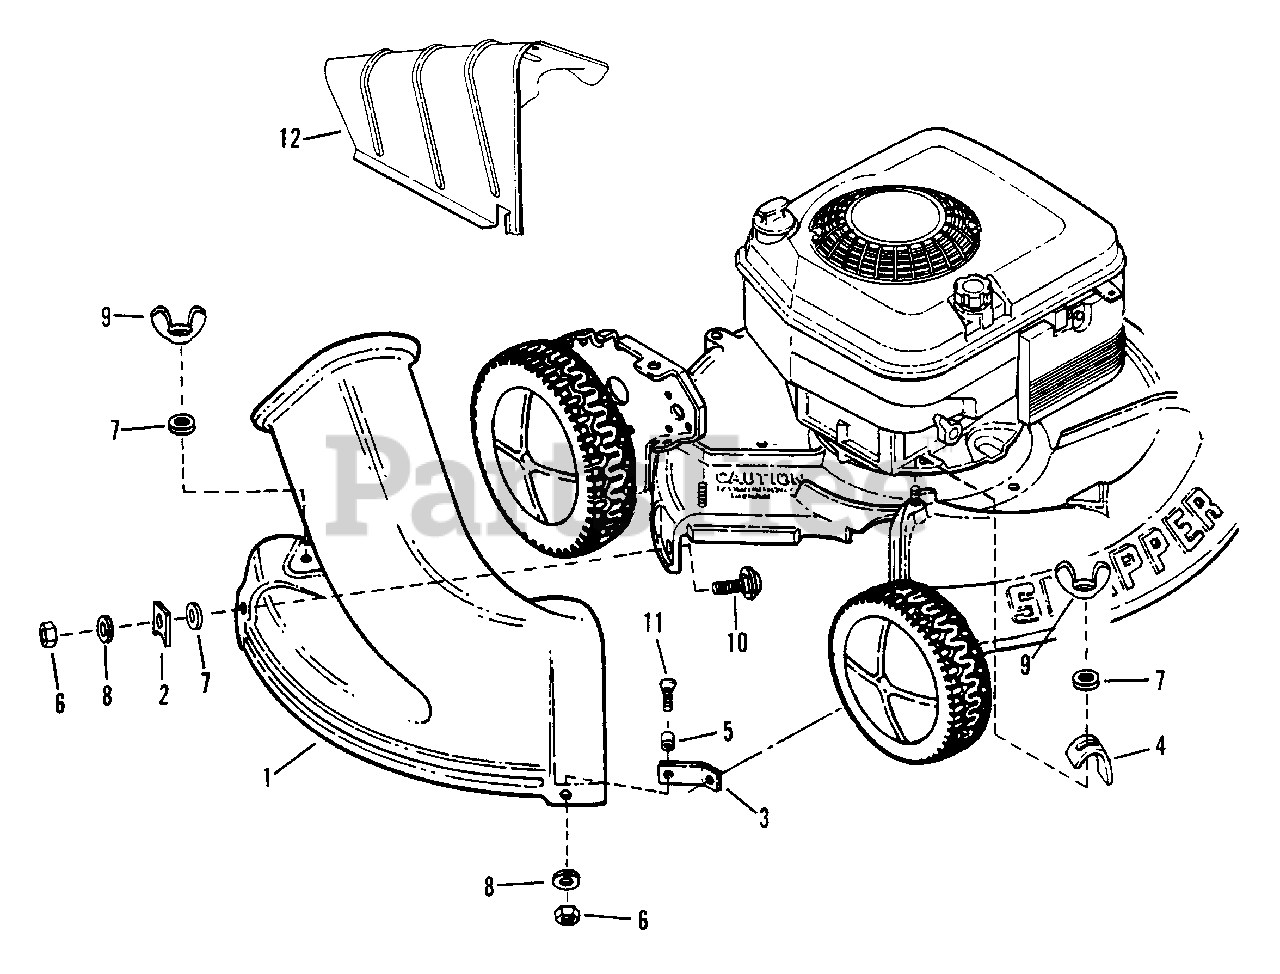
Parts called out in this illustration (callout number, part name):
1	ADAPTER, Grass Bag
2	PLATE, Guide
3	BRACKET, Side
4	CLAMP
6	NUT, 5/16-18 Hex
7	WASHER, 5/16 Flat
8	WASHER, 5/16 Split Lock
9	NUT, 5/16-18 Nylok Wing
10	BOLT, 5/16-18 x 1" Carriage
11	SCREW, 5/16-18 x 1-1/8" Flat Head
12	KIT, Side Chute
